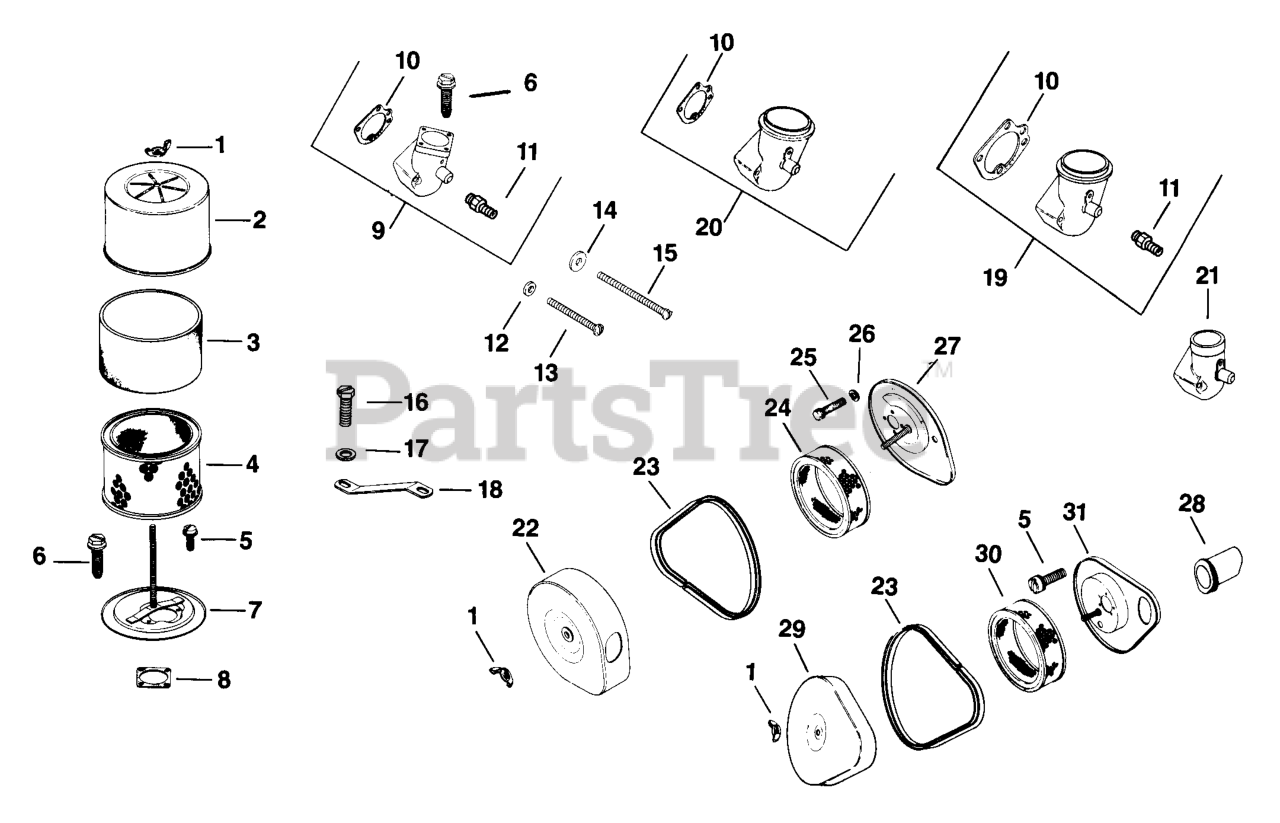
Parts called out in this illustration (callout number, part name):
11	CONNECTOR
12	WASHER, INT TOOTH LOCK #10
13	SCREW, SLT PAN HD 10-32X1 1/2" USE 25 086 63-S
14	WASHER, FLAT 3/16"
15	SCREW, SLT PAN HD 10-32X2 1/4"
19	KIT, ELBOW - DISCONTINUED
